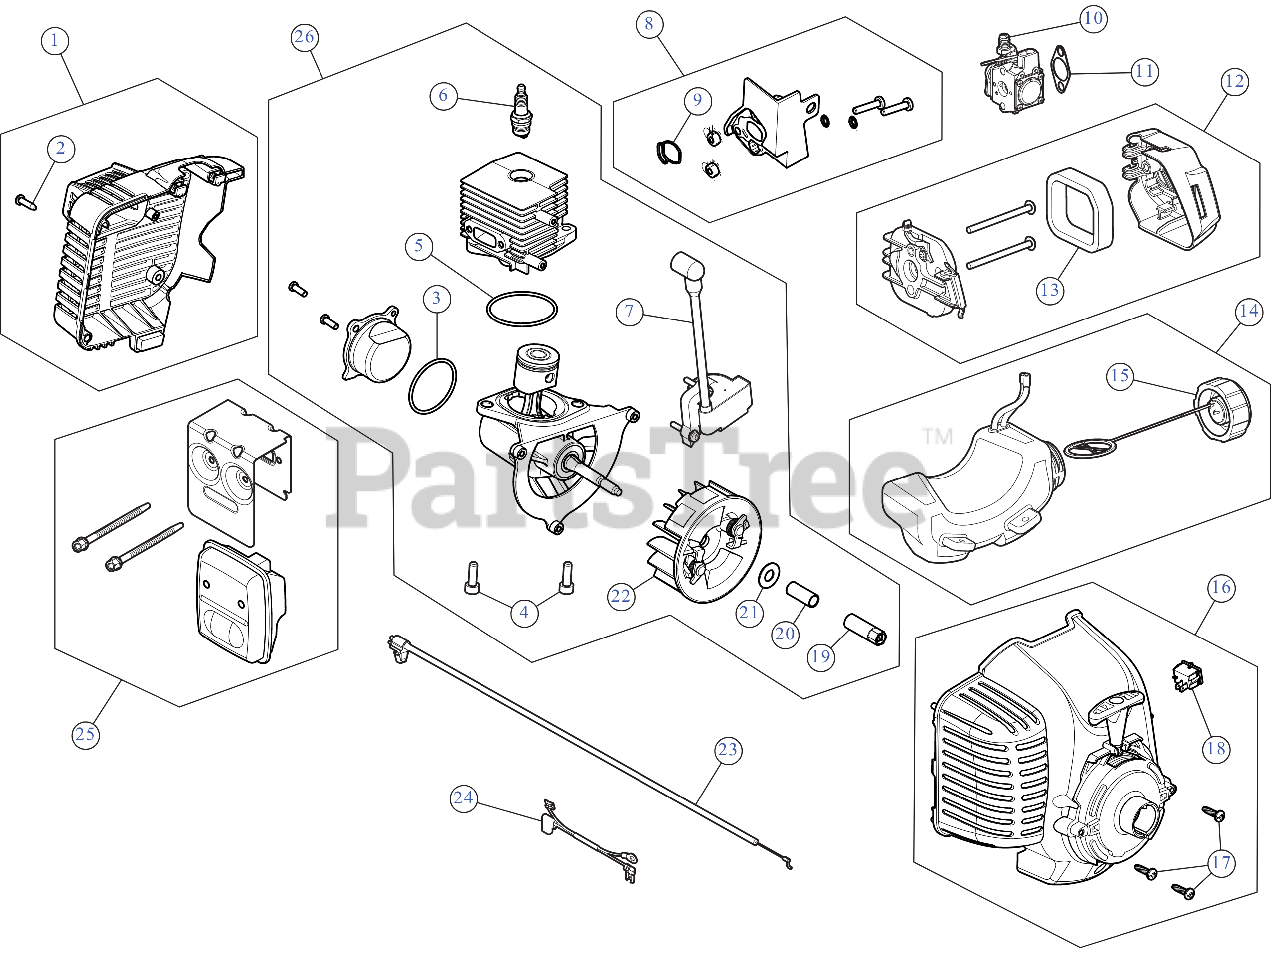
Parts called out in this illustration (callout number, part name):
1	HOUSING ASSEMBLY RR
2	SCREW, #8-16X.750 PH
3	O-RING SEAL CRANKCASE
4	SCREW 5/16-18x3/4 T40
5	O-RING SEAL CYLINDER
6	SPARK PLUG
7	MODULE ASSEMBLY
8	INTAKE ASSEMBLY
9	INSL/CYL SEAL
10	CARB ASSEMBLY
11	GASKET CARB
12	AIRCLEANER COVER ASSEMBLY
13	AIR FLITER
14	FUEL TANK ASSEMBLY
15	FUEL CAP ASSEMBLY
16	STARTER HOUSING ASSEMBLY
17	SCREW #
18	SW, MOMENTARY ON/O
19	POWER SHAFT ADAPTER
20	SPACER CRANKSHAFT
21	FLAT WASHER
22	FLYWHEEL ASSEMBLY
23	THROTTLE CABLE
24	WIRE LEAD
25	MUFFLER ASSEMBLY
26	SHORT BLOCK
